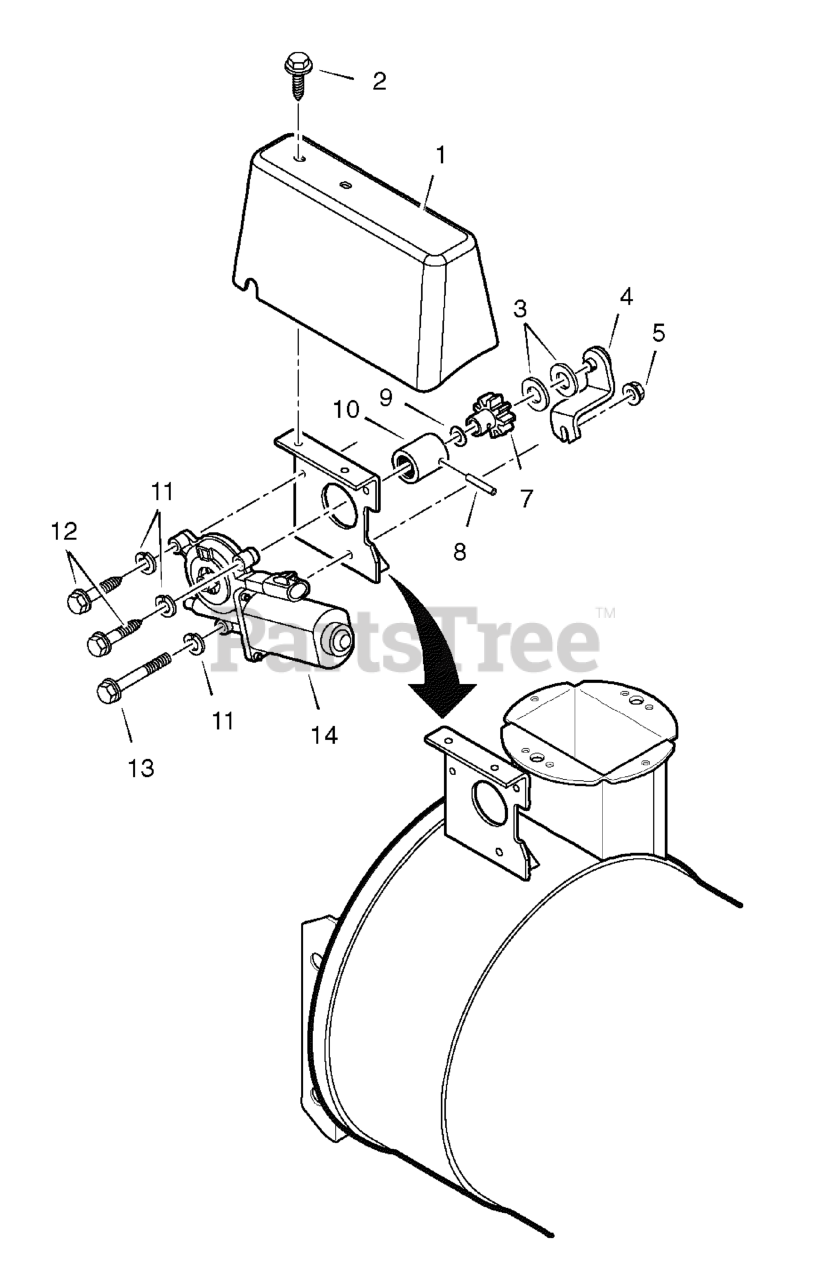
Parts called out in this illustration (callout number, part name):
1	COVER, MOTOR
3	WASHER
4	BRACE, CHUTE GEAR
8	PIN, SPRING
9	RING, RETAINER
12	SCREW, 25-20 X 1-1/4
13	CAPSCREW, HEX HEAD .25-20 x 1.50
14	MOTOR, ELECTRIC
